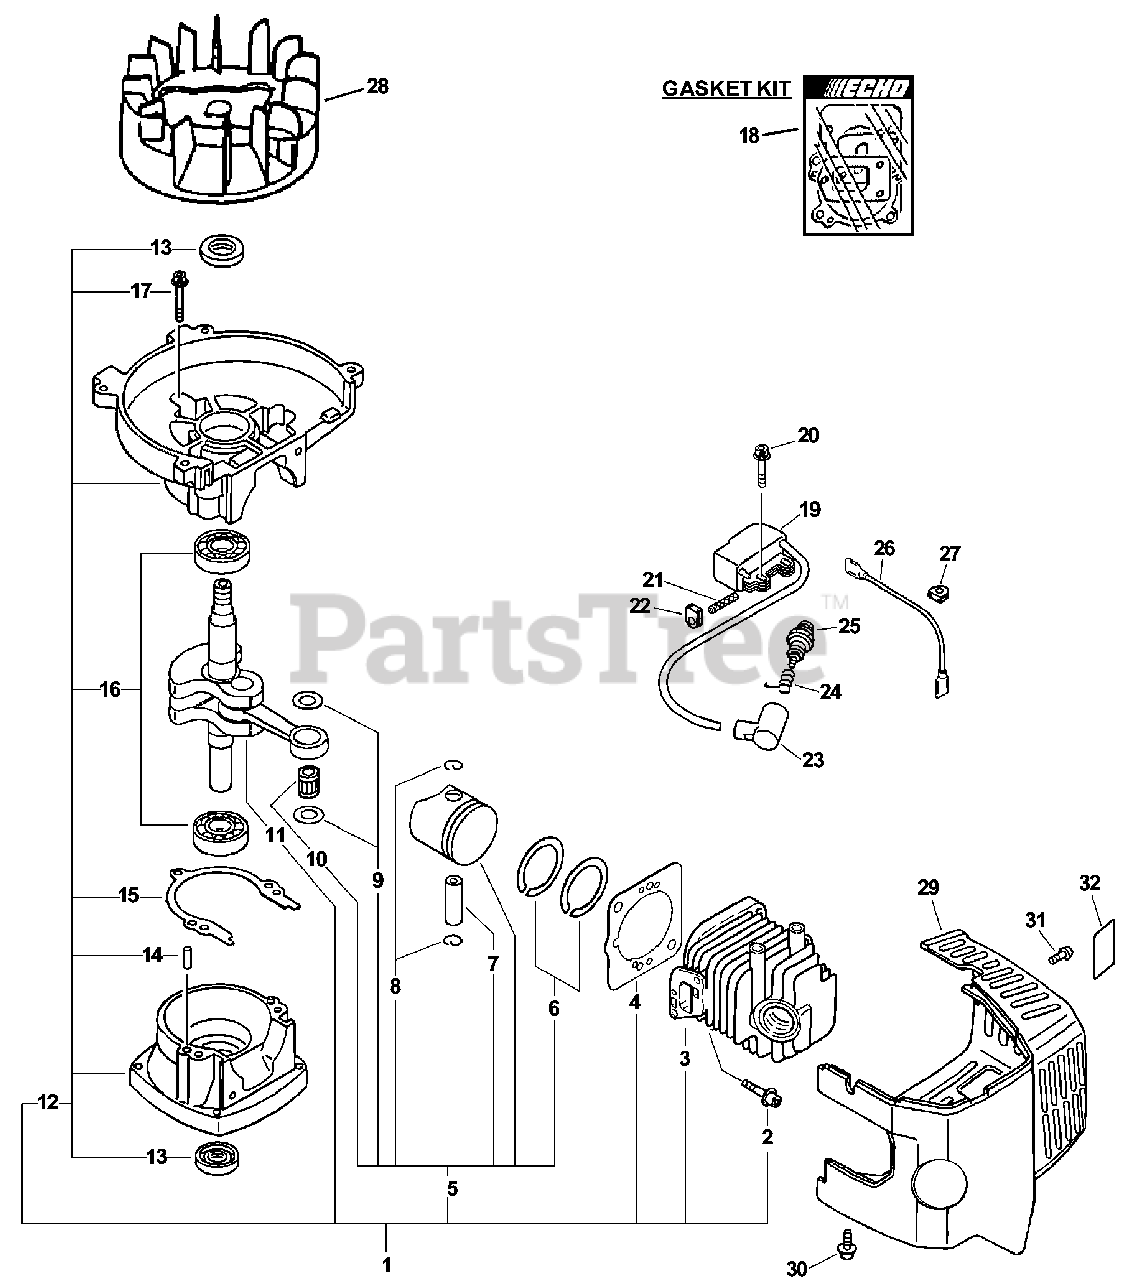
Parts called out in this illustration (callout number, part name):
1	SHORT BLOCK -- SB1067
2	SCREW - 5X22
3	CYLINDER
4	GASKET, CYLINDER
5	PISTON KIT
6	RING, PISTON
7	PIN, PISTON
8	RING, RETAINING
10	BEARING, NEEDLE - 8
11	CRANKSHAFT ASSY
12	CRANKCASE KIT
13	SEAL, OIL
14	PIN - LOCATING
15	GASKET, CRANKCASE
16	BEARING, BALL - 6201
17	SCREW - 5X28
18	GASKET KIT
19	COIL, IGNITION
20	SCREW - 4X20
21	TUBE, INSULATOR
23	CAP, SPARK PLUG
24	TERMINAL, SPARK PLUG CAP
25	SPARK PLUG -- BPM-8Y
25	SPARK PLUG -- BPMR-8Y
26	LEAD - IGNITION
28	FLYWHEEL
29	COVER, ENGINE - GRAY
30	SCREW - 4X20
31	SCREW - 4X8
32	LABEL - HOT SURFACE
